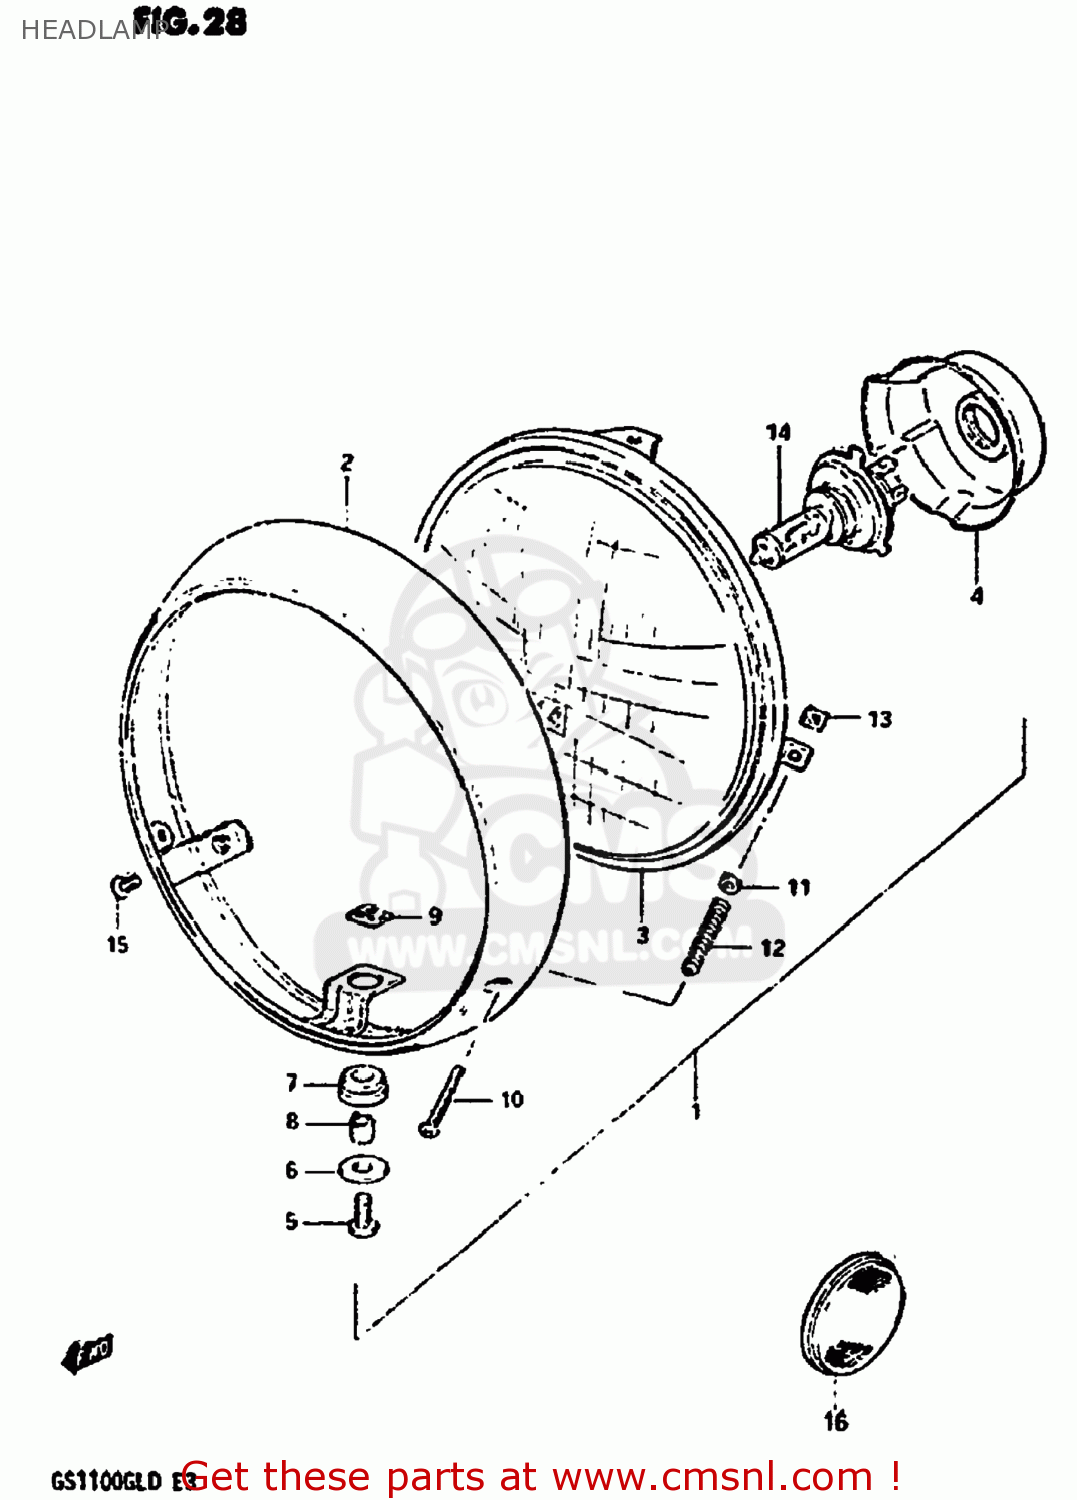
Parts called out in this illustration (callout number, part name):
1	HEADLAMP ASSEMBLY
2	RIM
3	LAMP UNIT
4	COVER,SOCKET
5	SCREW
6	WASHER
7	CUSHION
8	SPACER
9	NUT
10	SCREW
11	WASHER
12	SPRING
13	NUT,HEADLAMP ADJUSTER
14	BULB(12V60/55W,H4)
15	SCREW(5X12)
16	REFLEX REFLECTOR,RR
